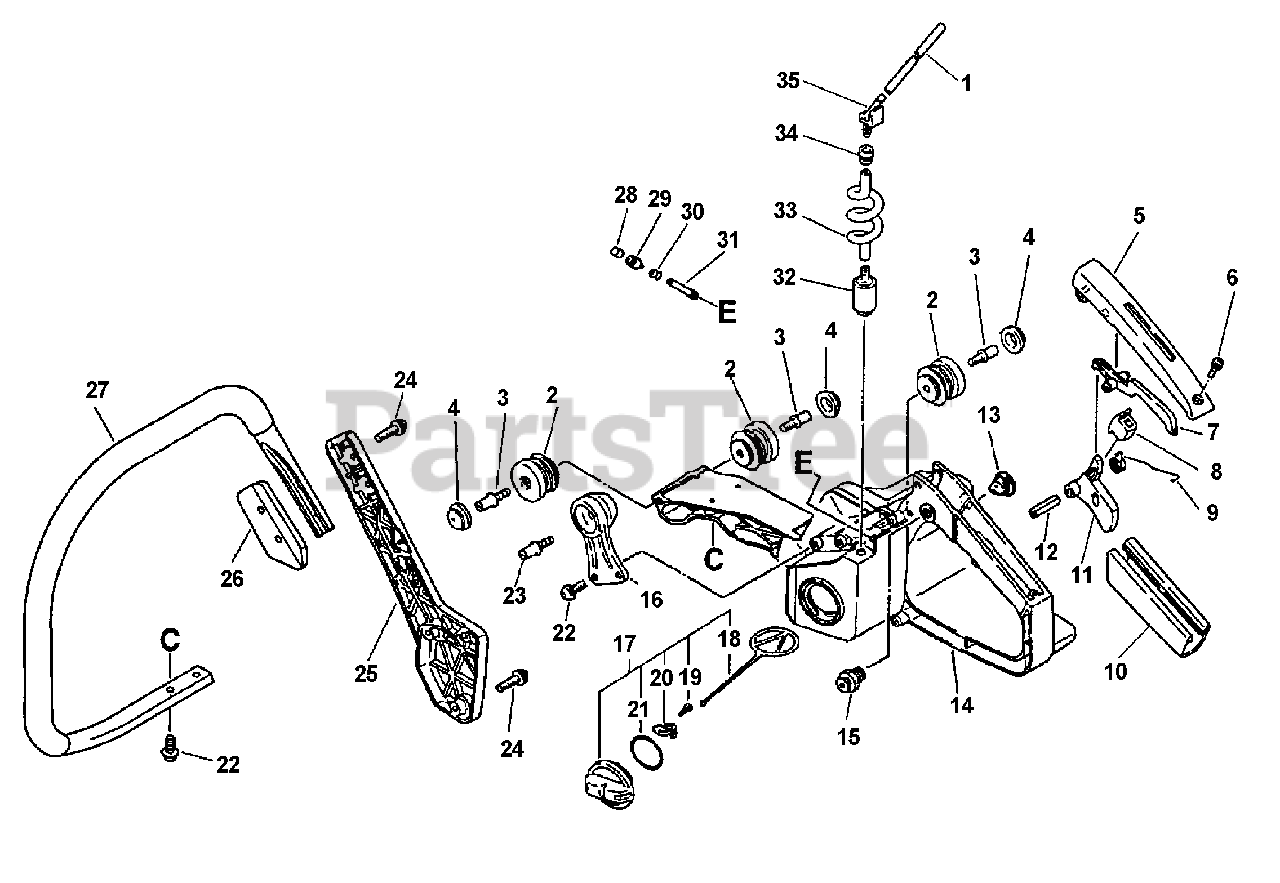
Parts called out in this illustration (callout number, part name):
1	PIPE - 3X6X100 -- BLACK
4	CAP, CUSHION
5	COVER, HANDLE
6	SCREW - 4X14
7	LEVER, TRIGGER LOCKOUT
9	SPRING, TRIGGER
10	GRIP, HANDLE
11	TRIGGER, THROTTLE
12	PIN - SPRING -- 5X25
14	HANDLE - REAR
15	LATCH, THROTTLE
17	CAP ASSY
18	CONNECTOR, CAP
19	SCREW - 3X8
20	RETAINER
21	O-RING - 29
22	SCREW - 5X14
24	SCREW - 5X20
25	BRACKET, HANDLE
26	BRACKET, HANDLE
27	HANDLE - FRONT
28	VENT, FUEL TANK
29	COVER, VENT
30	CLIP - 5.5
31	PIPE - VENT
32	FILTER, FUEL
33	PIPE - BLACK
34	GROMMET
35	CONNECTOR, PIPE
